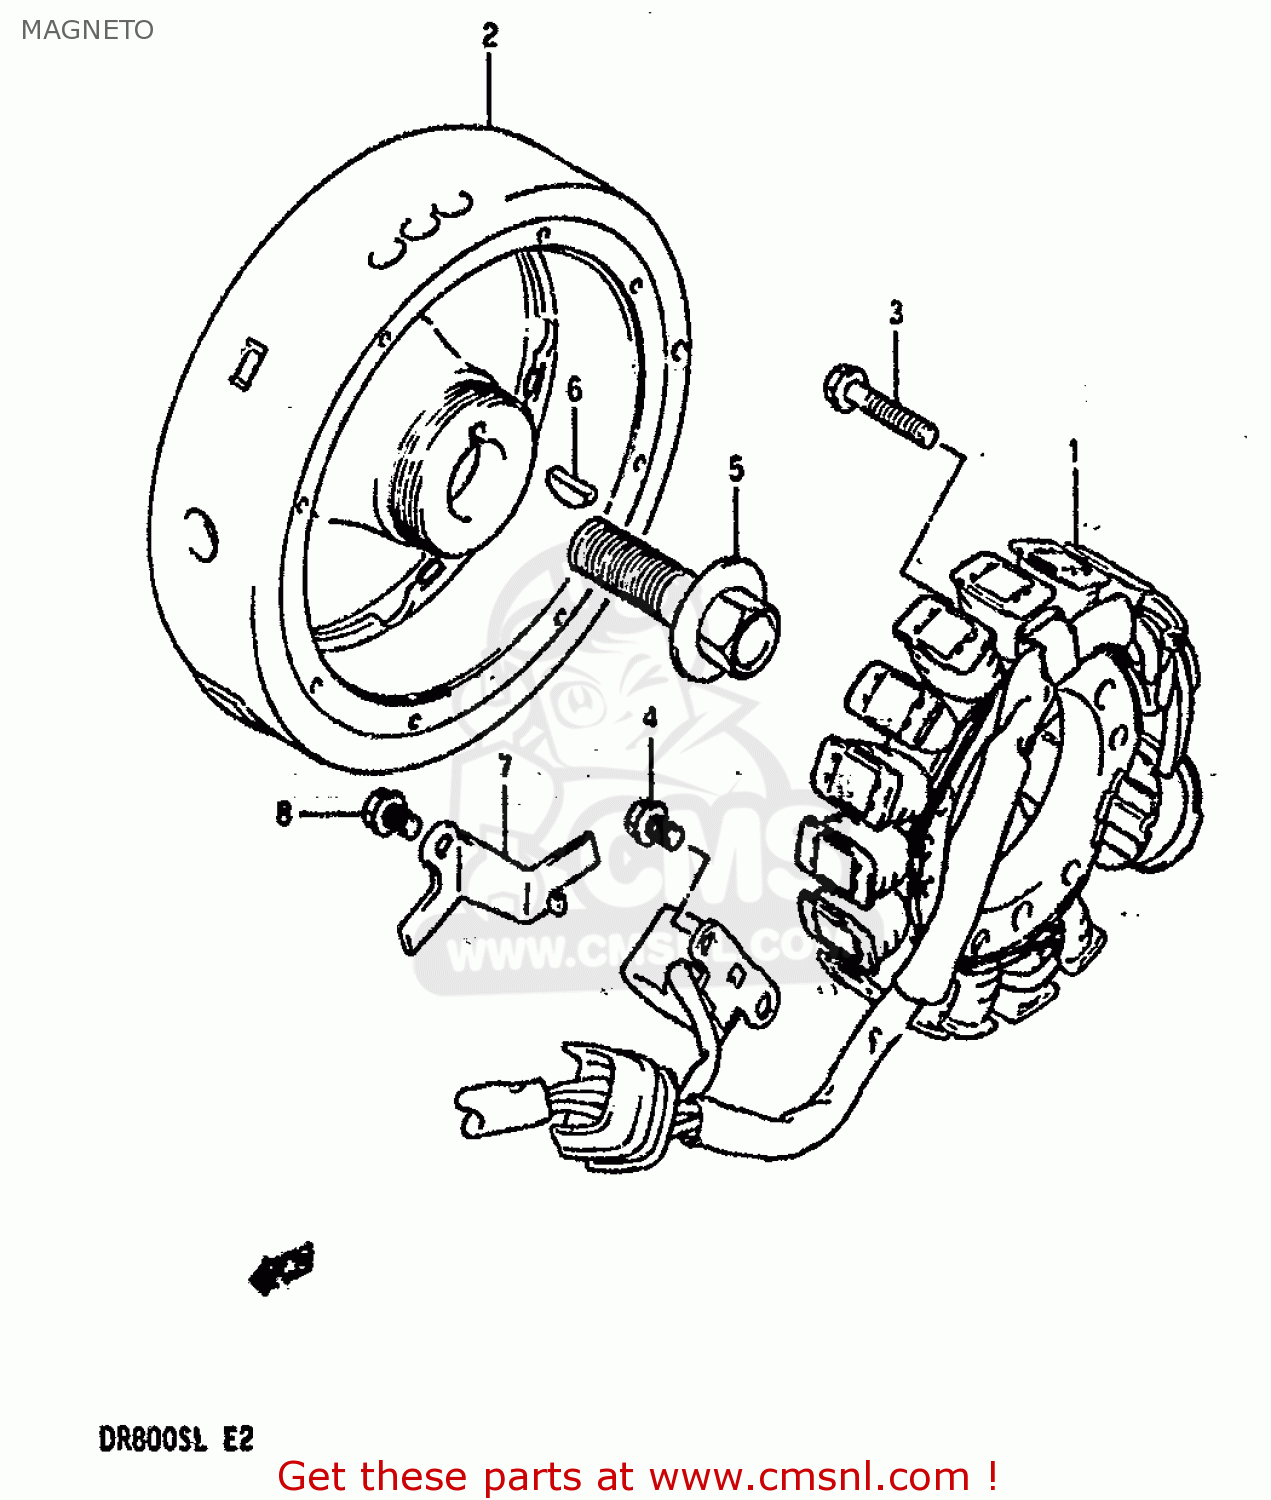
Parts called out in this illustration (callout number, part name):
1	STARTER ASSY
2	ROTOR
3	BOLT
4	BOLT
5	BOLT(14X43)
6	KEY
7	CLAMP,MAGNETO LEAD WIRE
8	BOLT
